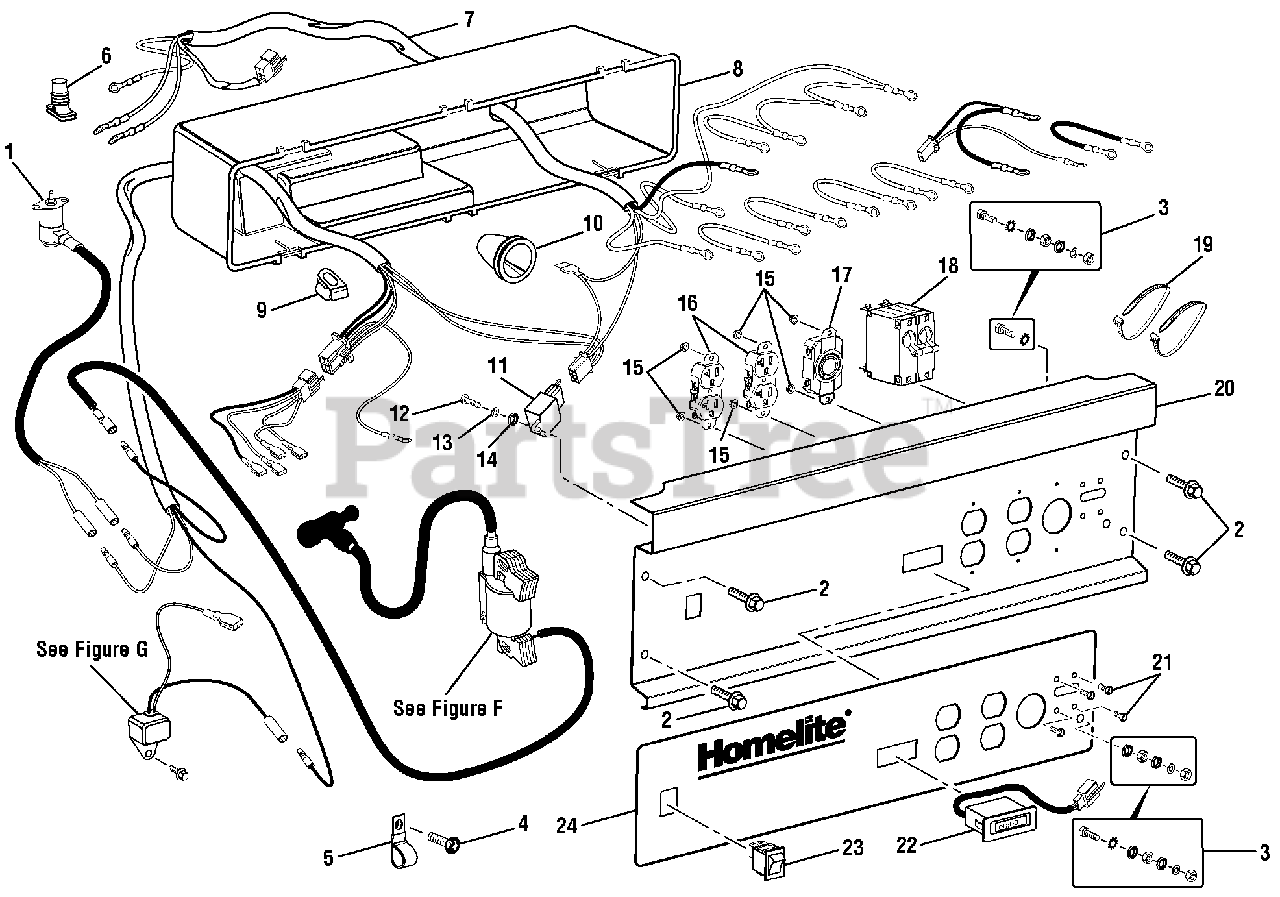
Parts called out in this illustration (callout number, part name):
1	Fuel Valve Solenoid
2	Bolt (M6 x 16 mm)
3	Ground Terminal Assembly
4	Screw (M6 x 12 mm)
5	Wire Clamp
6	Boot, Square
7	Wiring Harness Assembly
8	Cover, Control Panel Box
9	Boot, Switch Wire
10	Boot, Round
11	Diode Assembly
12	Screw (M4 x 15 mm)
13	Lock Washer (M4)
14	Washer (M4)
15	Hex Nut (M4)
16	120 V/ 20amp Duplex Receptacle
17	220 V/ 30amp Twist Lock Receptacle
18	Circuit Breaker, 2 pole 25 amp
20	Control Panel
21	Screw (M3 x 6 mm)
23	Ignition Switch
24	Performance/Power Outlet Label
